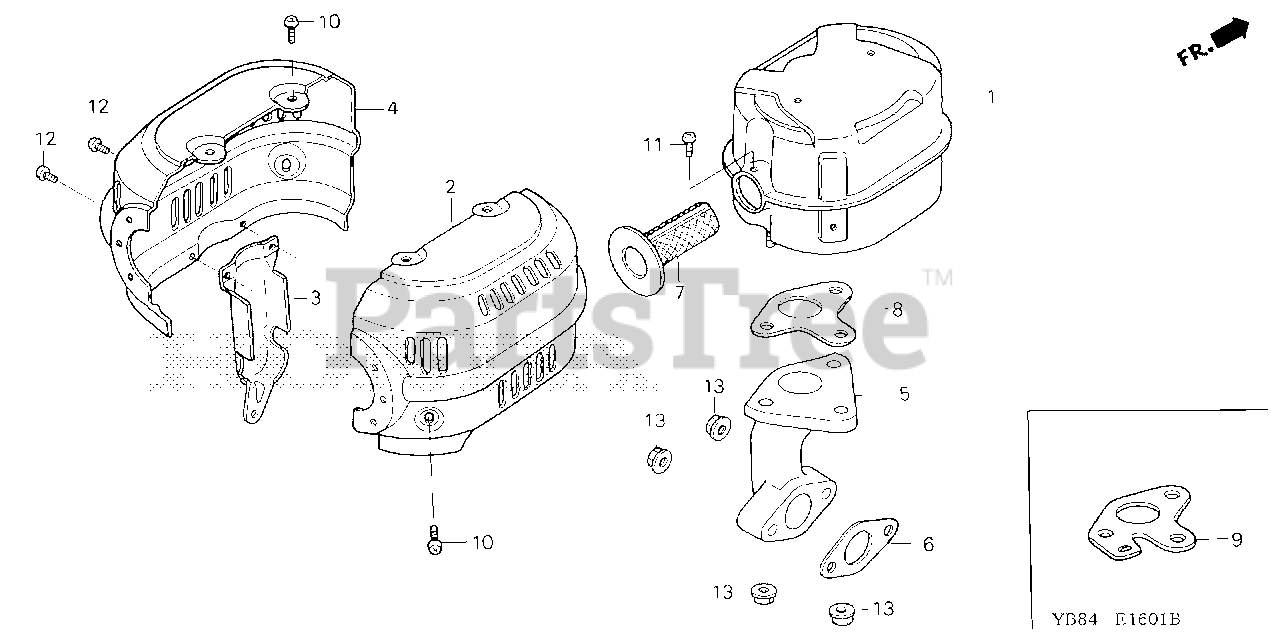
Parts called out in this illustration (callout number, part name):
2	PROTECTOR, R. MUFFLER (ALUMINIZED)
3	PROTECTOR, EX. PIPE (NOT AVAILABLE)
4	PROTECTOR, L. MUFFLER (ALUMINIZED)
6	GASKET, EX. PIPE
7	ARRESTER, SPARK
8	GASKET, MUFFLER
8	GASKET, MUFFLER (NIPPON LEAKLESS)
9	GASKET, MUFFLER (ARRESTER) (NIPPON LEAKLESS)
10	SCREW, TAPPING (5X8)
11	SCREW, TAPPING (4X6)
12	SCREW, PAN (5X8)
13	NUT, FLANGE (8MM)
